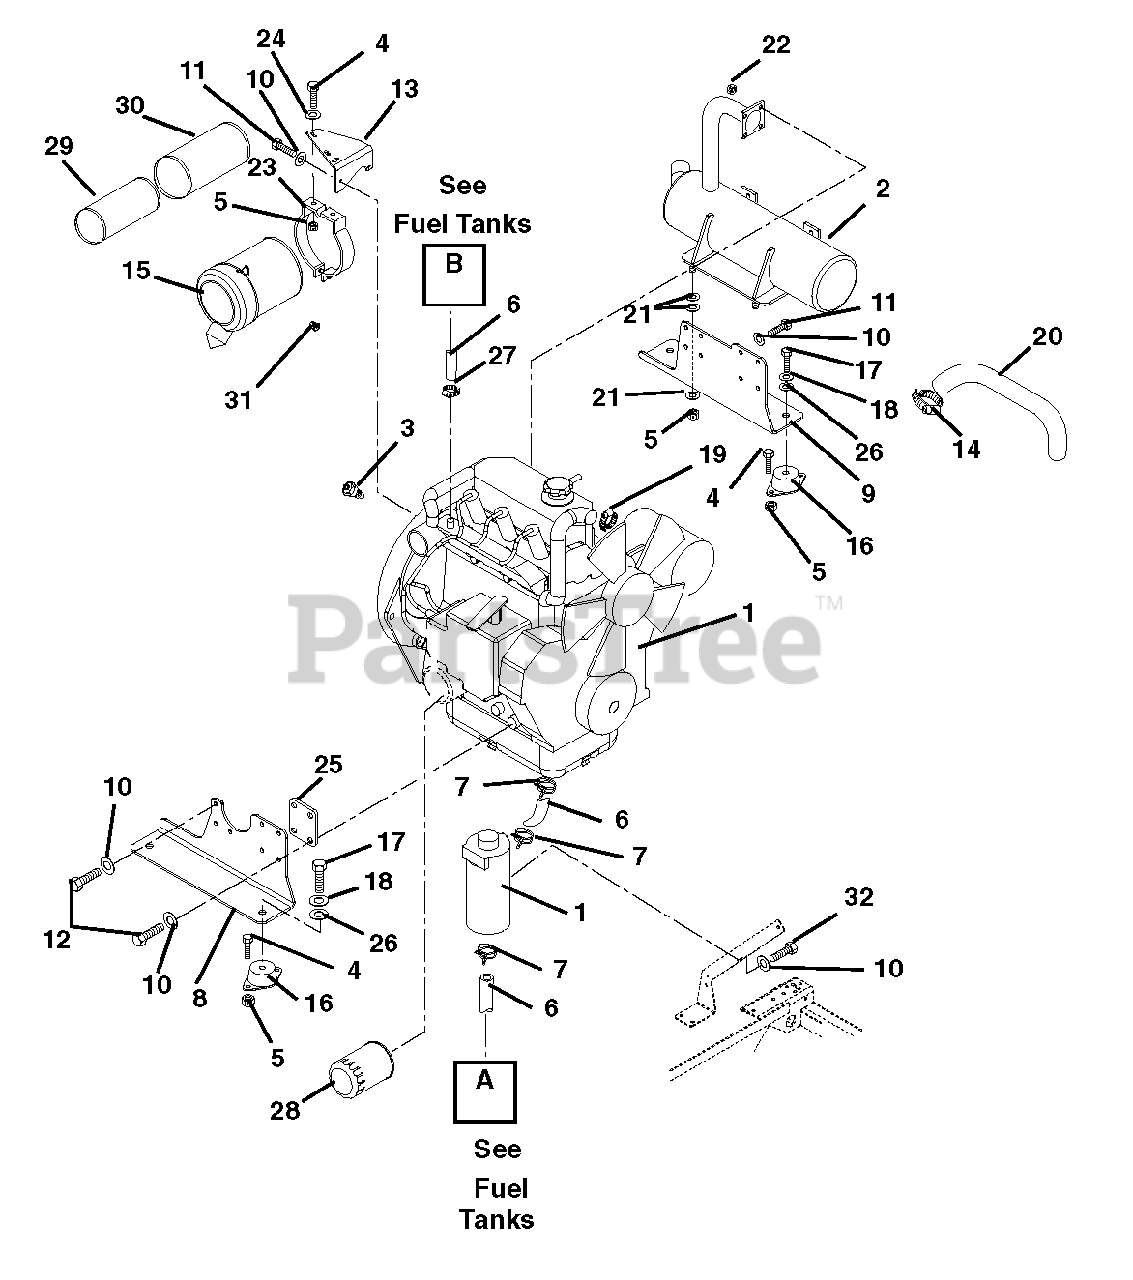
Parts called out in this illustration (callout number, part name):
1	Engine, 27HP Daihatsu Diesel (950D) (316, 322)
2	Muffler (316, 322)
3	Sender, Temperature
4	Bolt, Hex .31-18 x .75 Grade 5
5	Nut, Locking Top Flange .31-18
6	Gas Line, Bulk .31" ID
7	Hose, Clamp
8	Mount, Engine Right Hand
9	Mount, Engine Left Hand
10	Washer, Lock .31 x .078 Regular
11	Bolt, Hex M8-1.25 x 20
12	Bolt, Hex M8 x 1.25 x 25 Grade 8
13	Bracket, Air Cleaner
14	Clamp, 2.50" Dia. Hose
15	Assembly, Air Cleaner
16	Mount, Engine
17	Bolt, Hex .50-20 x 1.00 Grade 5
18	Washer, Locking .50 x .125 Regular
19	Clamp, Hose 1.50 x .81 x 1.42
20	Hose, Air Cleaner (316, 322)
21	Washer, Flat Steel .38 x .875 x .083
22	Nut, Locking Top M8-1.25
23	Bracket, Air Cleaner Mount
24	Washer, Flat Steel .38 x .875 x .083
25	Spacer, Engine Mounting
26	Washer, Flat Steel .531 x 1.06 x .095
27	Hose Clamp
28	Oil Filter
29	Element, Inner Safety
30	Element, Outer Primary
31	Plug, Pipe .125-27
32	Bolt, Hex M6-1 x 16
